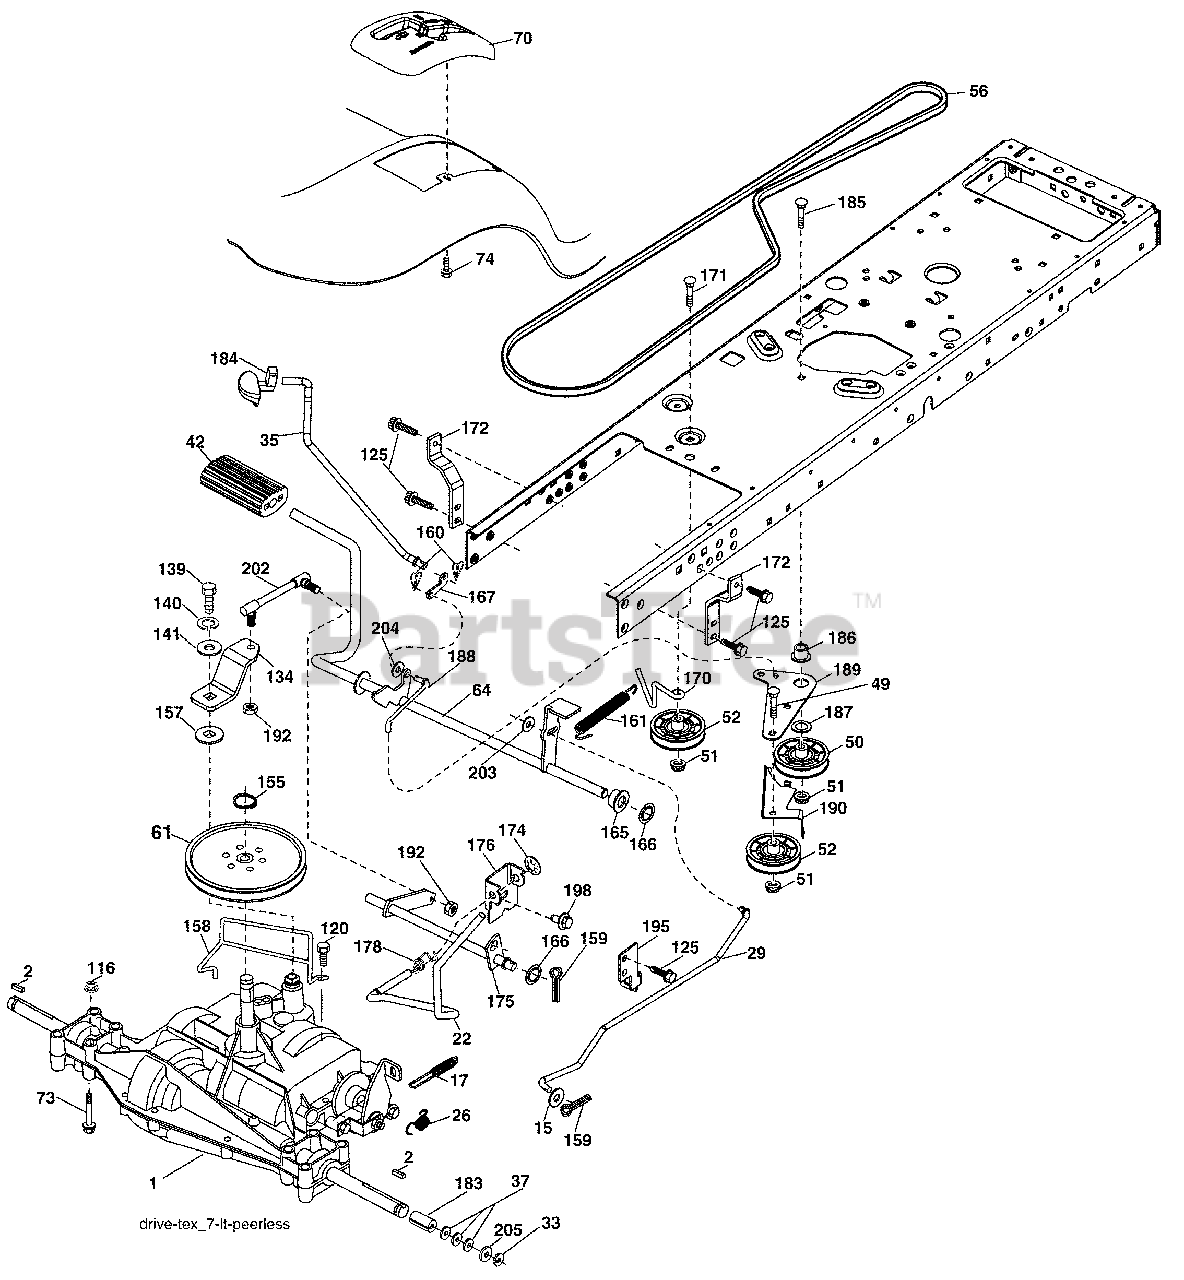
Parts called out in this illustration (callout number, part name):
2	Key Square
15	Washer 13/32 x 13/16 x 16 Ga.
17	Spring, Brake
26	Spring Brake Return
29	Rod, Brake
35	Rod, Brake, Park
37	Washer 25/32 x 1-1/4 x 16 Ga.
42	Cover, Foot Pedal
50	Pulley Idler Flat
51	Lock Nut 3/8-16
52	Idler V-Groove 910" Offset
56	V-Belt, Drive
61	Pulley transaxle
64	Shaft Asm. Pedal Brake Control
70	Console
73	Bolt Hex Flghd 5/16-18 x 3.0 Gr. 5
74	Screw 1/4 x 1/2
116	Nut Lock Hex Flange 5/16-18
120	Screw 5/16-18 x 3/4
125	Screw 5/16-18 x 3/4
139	Bolt 1/4-28 unf Gr. 8 w/Patch
140	Washer Lock Hvy Helical 1/4
141	Washer 9/32 x 3/4 x 10 Ga.
155	Ring Retainer
157	Washer Plate Shift
158	Belt Keeper
159	Pin Cotter 1/8 x 3/4
160	Retainer Clip
161	Spring, Return, Clutch
165	Busing Shaft Brake Hand Control
166	Nut Push .625
167	Latch Brake Parking
170	Keeper Belt Centerspan
172	Strap Torque LH
175	Shaft Asm. Shift
176	Arm Clevis Rod Shift
178	Spring Shift
183	Spacer Axle
184	Parking Brake Handle
186	Spacer Retainer
187	Washer
188	Link Clutch Ground Drive
189	Bellcrank Ground Drive
190	Keeper Bellcrank Ground Drive
192	Nut Lock Center 1/4-28 Fnthd
195	Bracket Brake Rod
198	Screw 7/16-14 x 7/8
202	Link Transaxle
203	Washer 11/32 x 11/16 x 16 Ga.
204	Stud Fastener
205	Washer 25/32 x 1-5/8 16 Ga.
